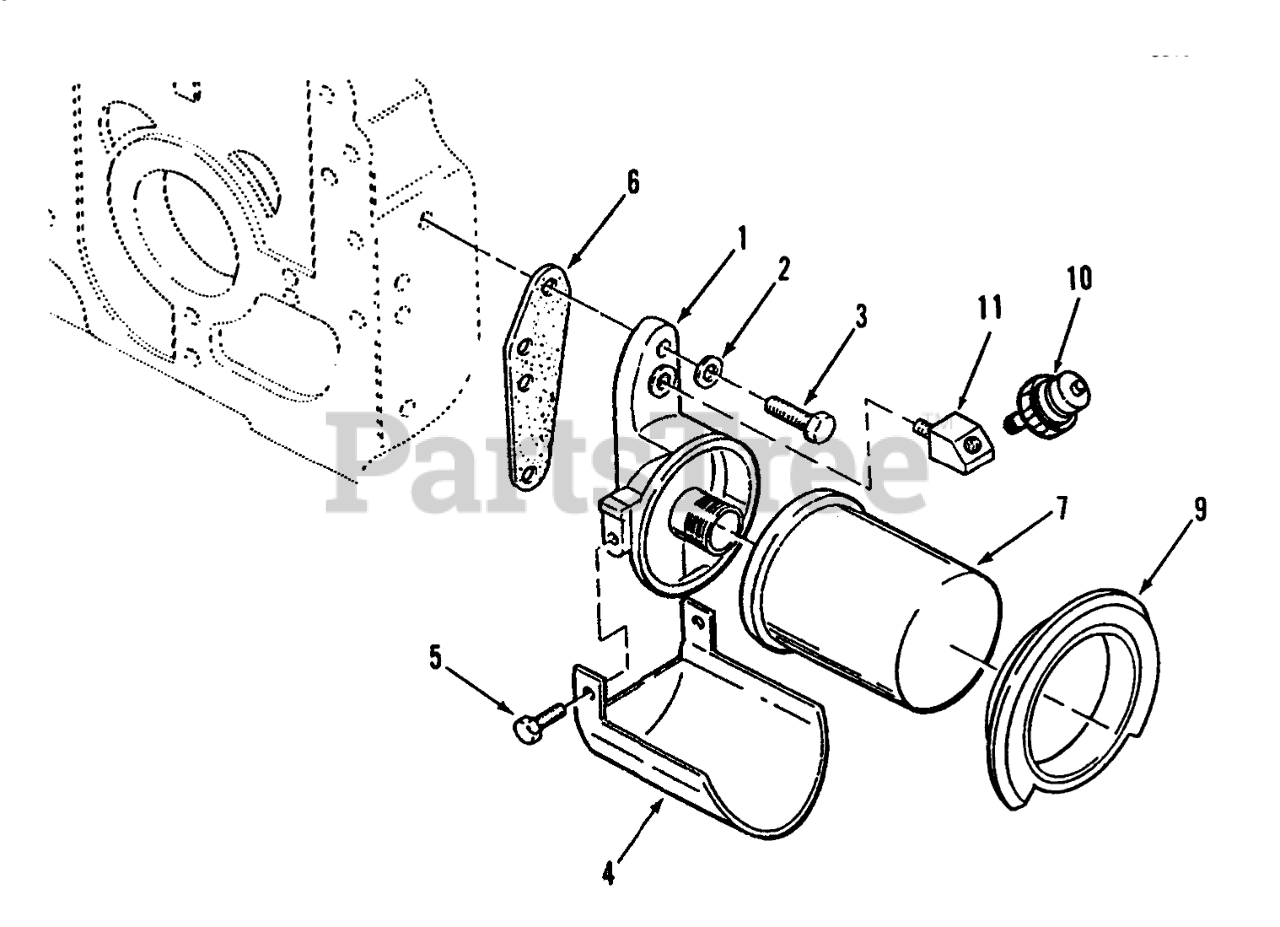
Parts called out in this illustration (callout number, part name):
1	ADAPTER-OIL FILTER
2	Washer
3	HHCS 5/16-18 X 1
4	OIL-FILTER DRAIN
5	SCREW-HH
6	Gasket
7	OIL FILTER
9	GASKET - AIR SEAL
10	SWITCH
11	45 DEG STREET ELBOW
